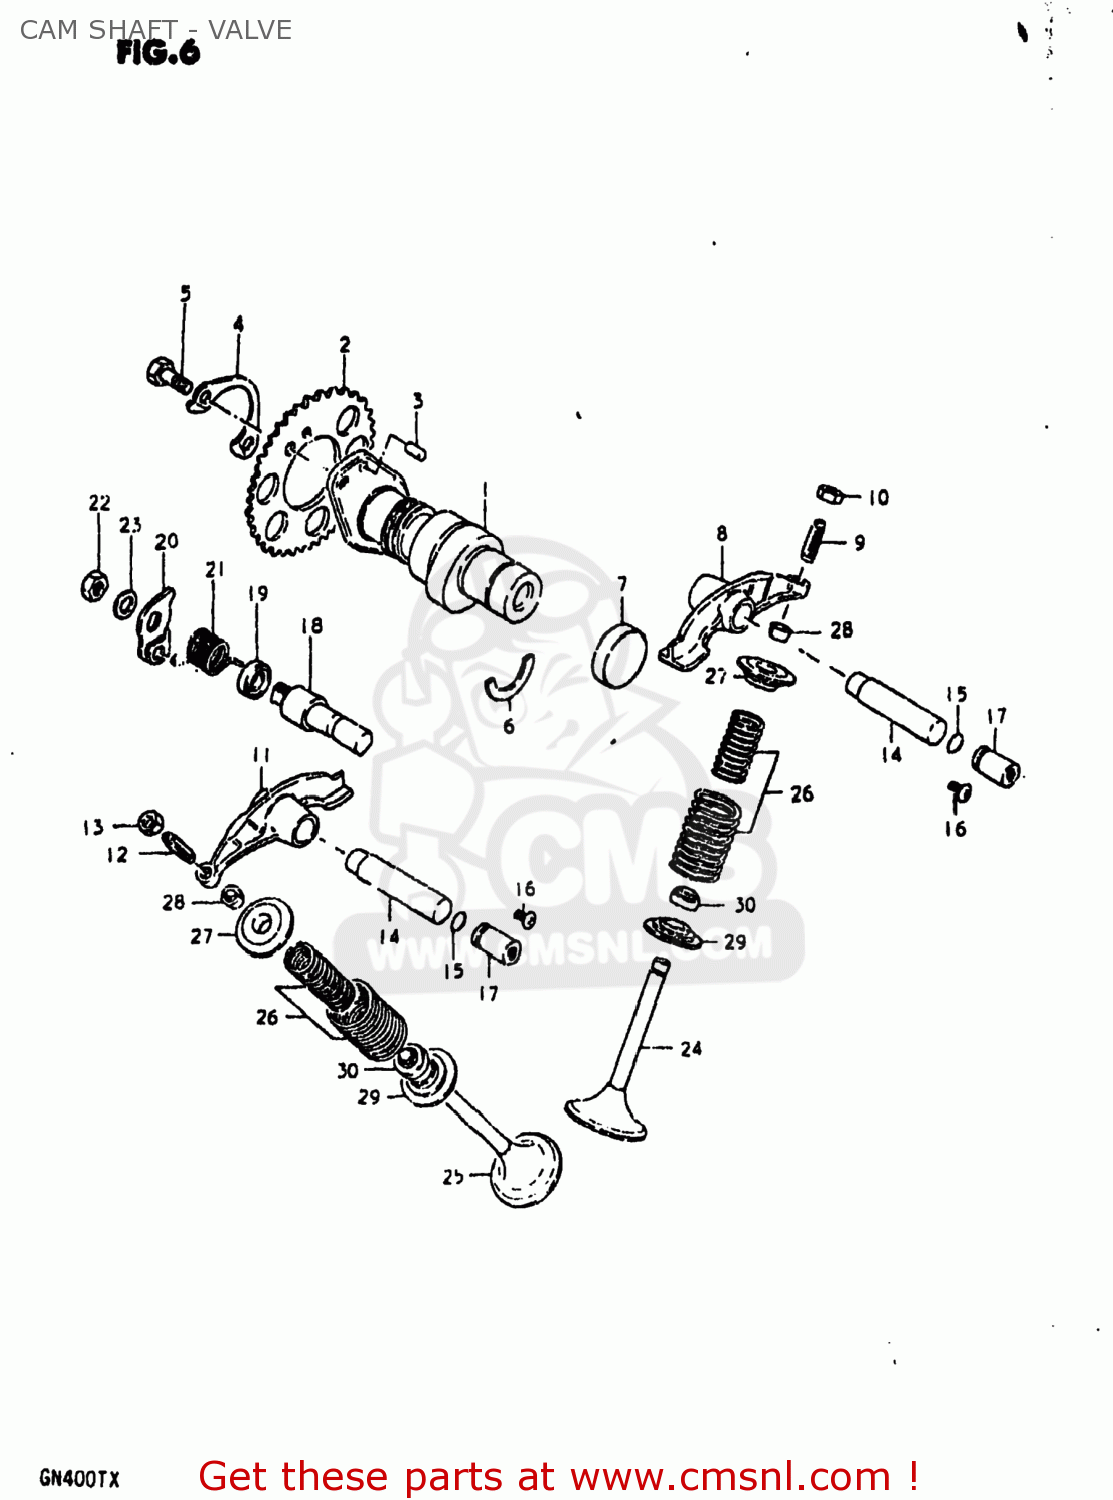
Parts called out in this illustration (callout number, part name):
1	CAMSHAFT
2	SPROCKET,CAMSHAFT
3	PIN
4	WASHER,CAM CHAIN SPROCKET
5	BOLT(6X12.5)
6	C RING
7	PLUG
8	ARM,VALVE ROCKER
9	SCREW,TAPPET ADJUSTING
10	NUT,ADJUSTING SCREW
11	ARM,VALVE ROCKER
12	SCREW,TAPPET ADJUSTING
13	NUT,ADJUSTING SCREW
14	SHAFT,VALVE ROCKER
15	O-RING
16	SCREW
17	CAP,ROCKER ARM SHAFT
18	SHAFT,DECOMPRESSION
19	OIL SEAL
20	LEVER,DECOMPRESSION SHAFT
21	SPRING
22	NUT 8MM
23	WASHER
24	VALVE,INTAKE
25	VALVE,EXHAUST
26	SHIM,TAPPET
27	RETAINER,VALVE SPRING
28	COTTER VALVE
29	SEAT,VALVE SPRING
30	SEAL,OIL(7X14.4X9)
